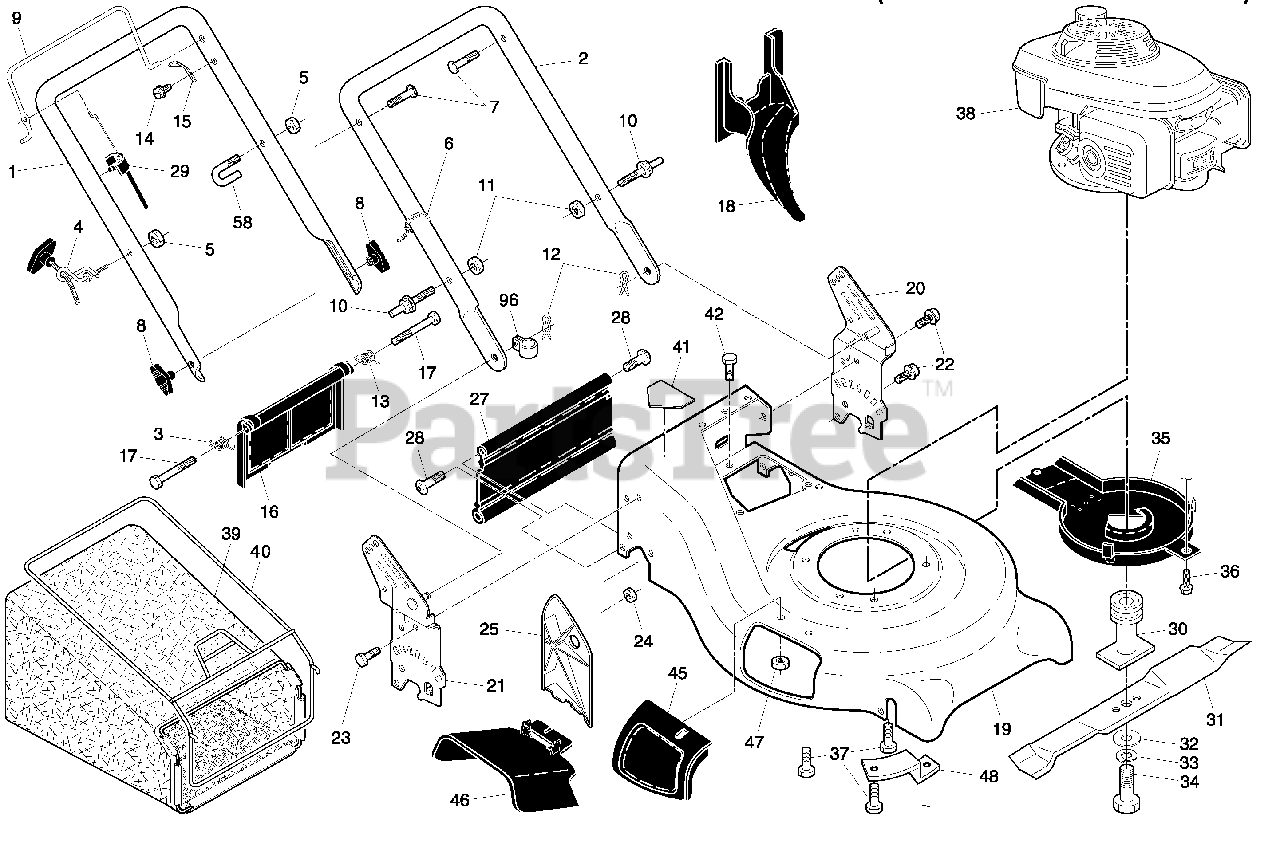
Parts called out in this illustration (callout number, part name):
1	Handle, Upper
2	Handle, Lower
3	Spring, Rear Door, RH
4	Rope Guide
5	Nut, Hex, with Lockwasher Insert 1/4-20
6	Wire, Tie
7	Bolt, Handle 5/16-18 x 2-5/8
8	Knob, Handle
9	Control Bar
10	Pin, Handle Adjustment
11	Nut, Hex
12	Cotter, Hairpin
13	Spring, Rear Door, LH
14	Screw
15	Bracket, Upstop
16	Rear Door Assembly
17	Bolt, Rear Door
18	Plug, Mulcher
19	Kit, Housing
20	Handle Bracket Asembly, LH
21	Handle Bracket Assembly, RH
22	Screw, Hex Washer Head
23	Bolt, Hex Head 5/16-18 x 5/8
24	Nut, Hex, with Lockwasher Insert 5/16-18
25	Baffle, Side
26	Screw, Hi-Lo Thread #12 x 5/8
27	Skirt, Rear
28	Screw, Hinge 1/4-20 x 1.25
29	Cable, Operator Presence
30	Blade Adapter / Pulley
31	Blade, 21"
32	Washer
33	Washer, Lock
34	Bolt, Hex Head
35	Debris Shield
36	Bolt
37	Bolt, Engine
39	Grassbag
40	Frame, Grassbag
41	Danger Decal
42	Screw
45	Mulcher Door
46	Discharge Guard
47	Nut, Hex
48	Mounting Bracket, Debris Shield
58	Clip, Packaging
96	Clip, Cable
96	Operator's Manual, English
96	Operator's Manual, French
